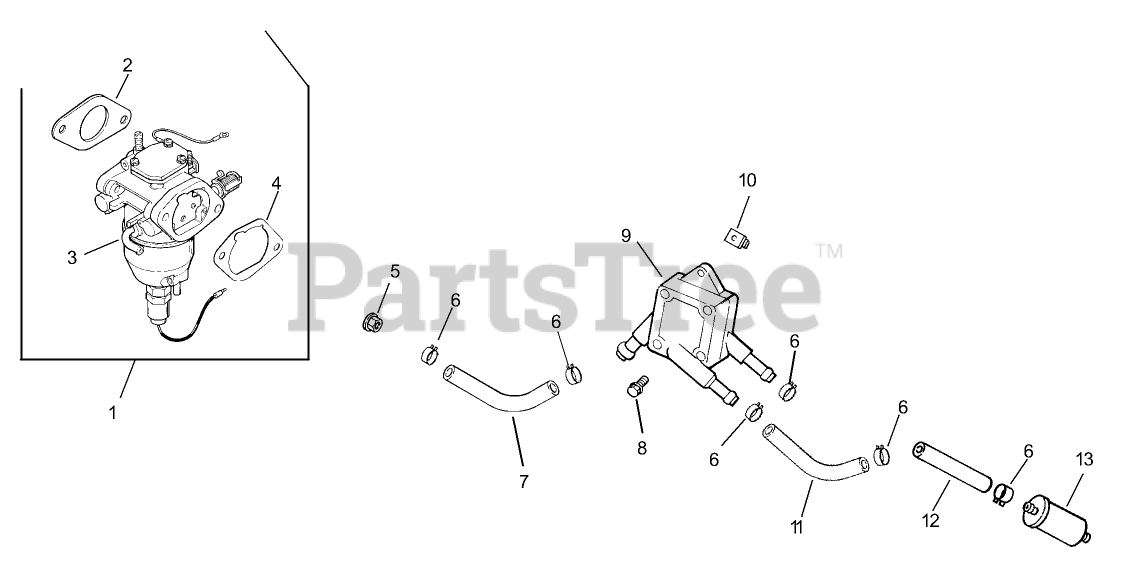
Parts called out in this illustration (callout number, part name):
1	Kit, carburetor w/gaskets (Includes 2-4)
2	Gasket-carburetor
3	Carburetor assembly (For information only not available separately)(Service with kits 24 234 02-S, 24 757 18-S, 24 757 19-S, 24 757 20-S, 24 757 21-S and 24 757 22-S)
4	GASKET-BASE, AIR CLEANER
5	NUT-FLANGE (M6X1.0)
6	CLAMP-HOSE, SPRING (1/2)
7	Line, fuel 6-1/4
8	SCREW-TAP (M6X1.7X18)
9	PUMP-FUEL
10	Nut-Plastic
11	Line, fuel 10-1/2
12	Line, fuel 12"
13	Filter-Fuel
